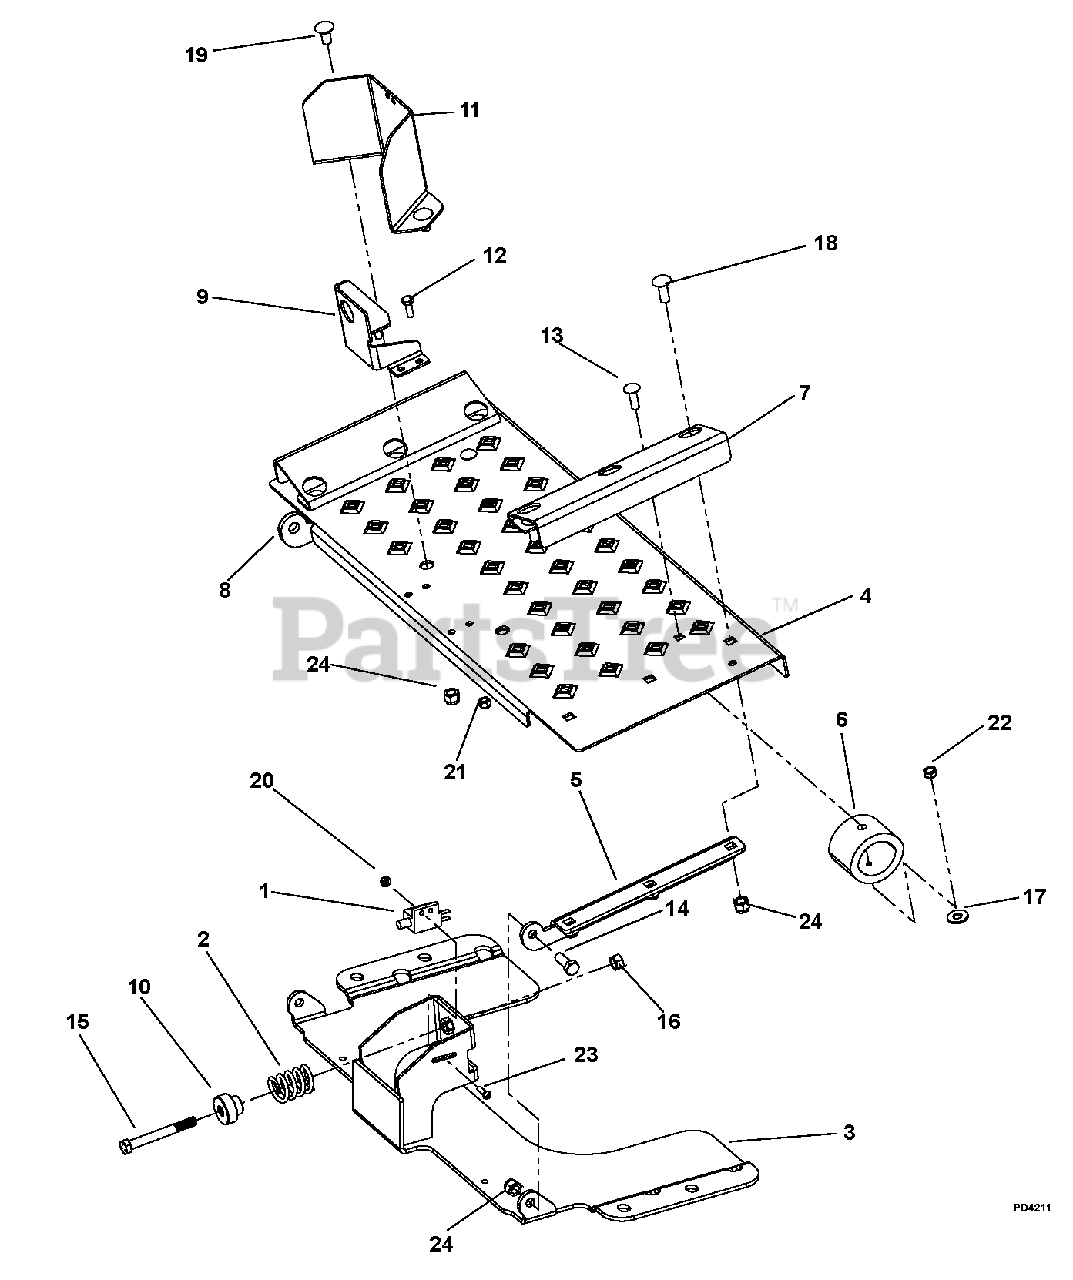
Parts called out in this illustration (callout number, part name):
1	Switch-Single Pole w Cover
3	Weldment, Platform
4	Plate, Platform
5	Plate, Platform Tab
6	Bumper, MINER GBR-6
7	Wedge, Platform
8	Plate, Platform Tab
9	Anchor, Operator Presence Control
10	Washer, Spring
11	Cover, Operator Presence Control
12	Bolt, Hex M12 x 1.75 x 25
13	Bolt, Round Head Square Neck .31-18 x 1.00
14	Bolt, JDS19-16 UNC
15	Bolt, Hex .38-16 x 3.25
16	Nut, Hex .31-18
17	Washer, Flat .38 x .875 x .083
18	Bolt, Round Head Square Neck .31-16 x 1.00
19	Bolt, Round Head Square Neck .31-16 x .75
20	Jam Nut, Locking, Center .375-16
21	Nut, Locking, Nylon .250-20
22	Nut, Locking, Nylon .312-18
23	Screw, Machine 10-24 x .62 Pan Head
24	Nut, Locking, Nylon .38-16
